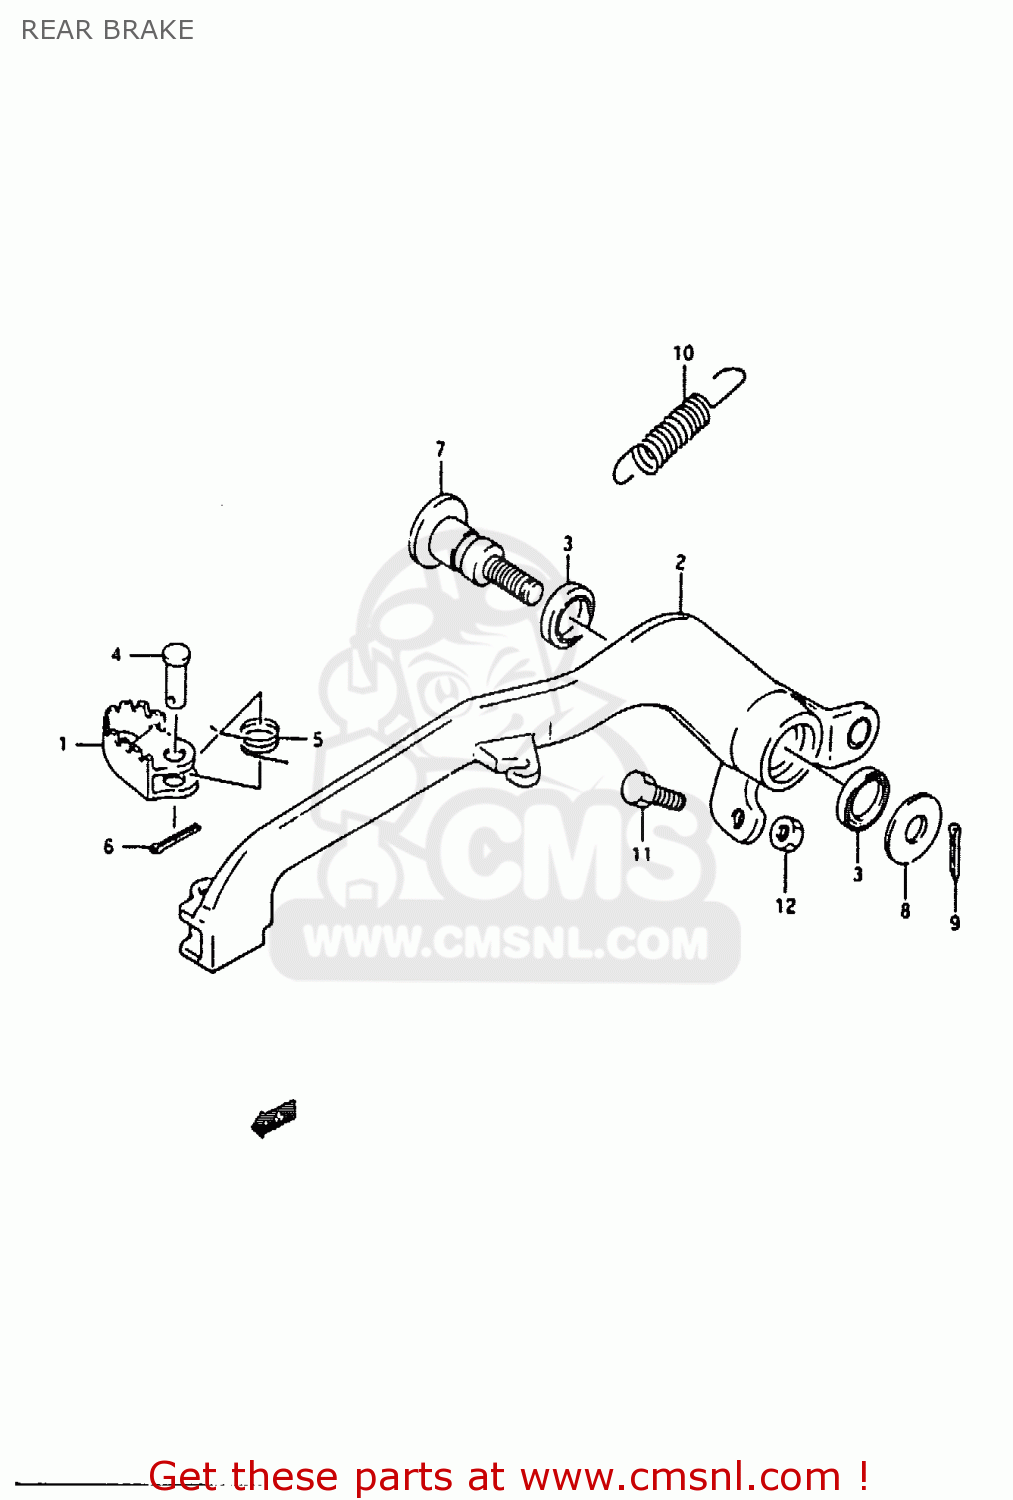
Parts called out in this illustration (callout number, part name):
1	PEDAL,BRAKE
2	ARM,BRAKE PEDAL
3	SEAL,OIL(15X21X3)
4	PIN(6X23.5)
5	SPRING
6	PIN
7	SHAFT,BRAKE PEDAL
8	WASHER
9	PIN 20X20
10	SPRING
11	BOLT(6X23)
12	NUT
